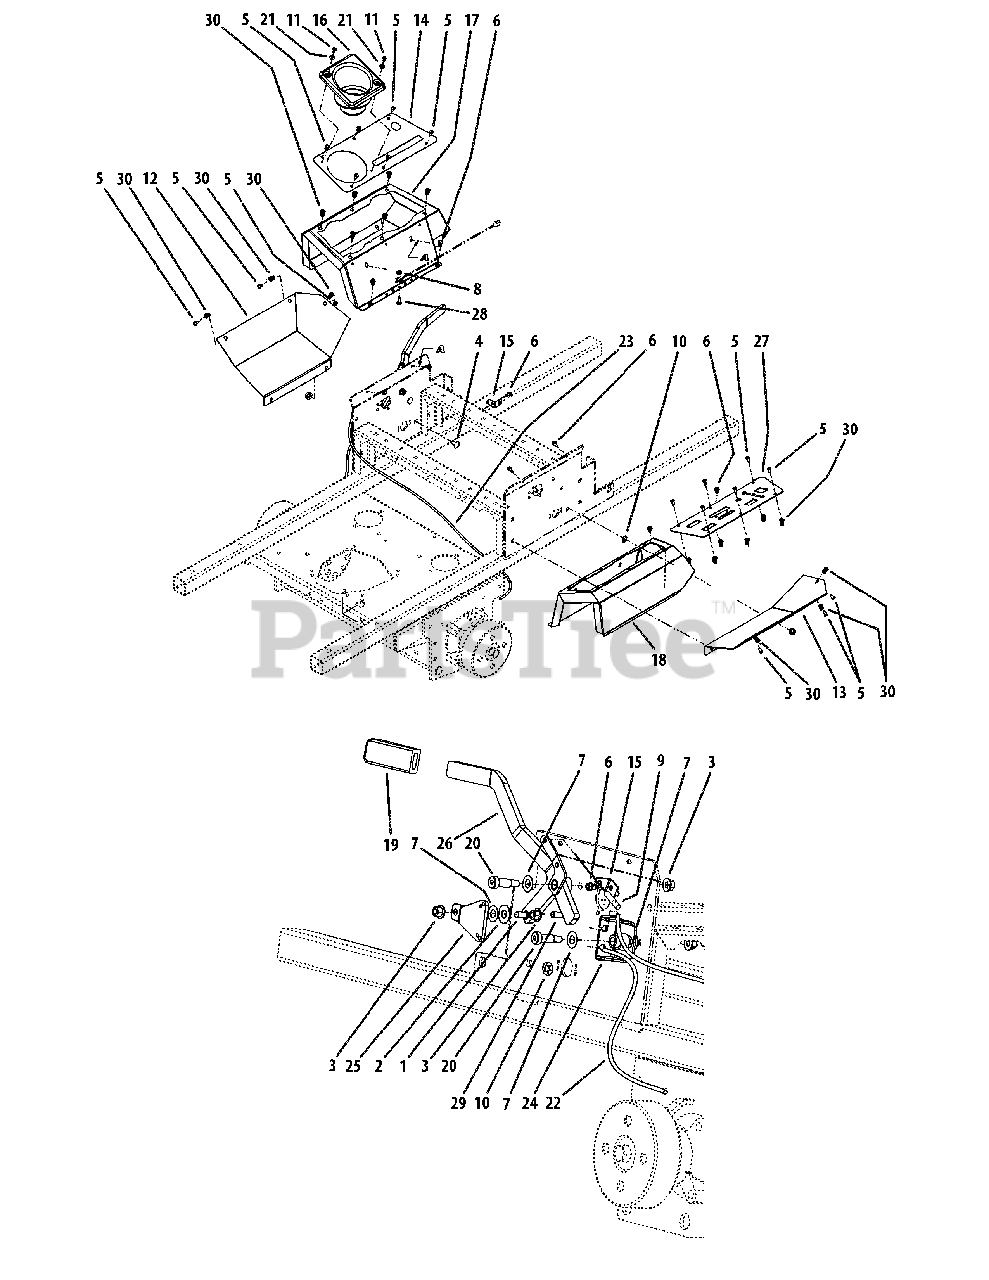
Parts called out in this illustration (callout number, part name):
1	Shoulder Bolt, 1/2 x 1/2
2	Washer, 1/2 Zinc
3	Flange Lock Hex Nut, 3/8-16
4	Carriage Bolt, 3/8-16 x .75
5	Screw Button Head, 1/4-20 x .5
6	Screw, TT, 1/4-20, 0.5, Washer
7	Washer, .508 ID x 1.0 OD x .020
8	Hex Flange Lock Nut, 1/4-20
9	Left Hand Brake Cable
10	Push Retainer, 3/8
11	Screw, #10-32 x 0.500
12	Lower Panel, LH
13	Lower Panel, RH
14	Control Panel Cover, LH
15	Brake Cable Mounting Bracket
16	Cup Holder
17	Control Panel, LH
18	Control Panel, RH
19	Parking Brake Grip
20	Shoulder Bolt, 1/2 x 1.00, 3/8-16
21	Washer, 3/16
22	Brake Cable, LH
23	Brake Cable, RH
24	Brake Cable Bracket
25	Centering Bracket
27	Control Panel Cover, RH
28	Screw, Hex, Cap, 1/4-20 x .75
29	Carriage Bolt, 3/8-16, 1.00
30	U-Nut, 1/4-20
